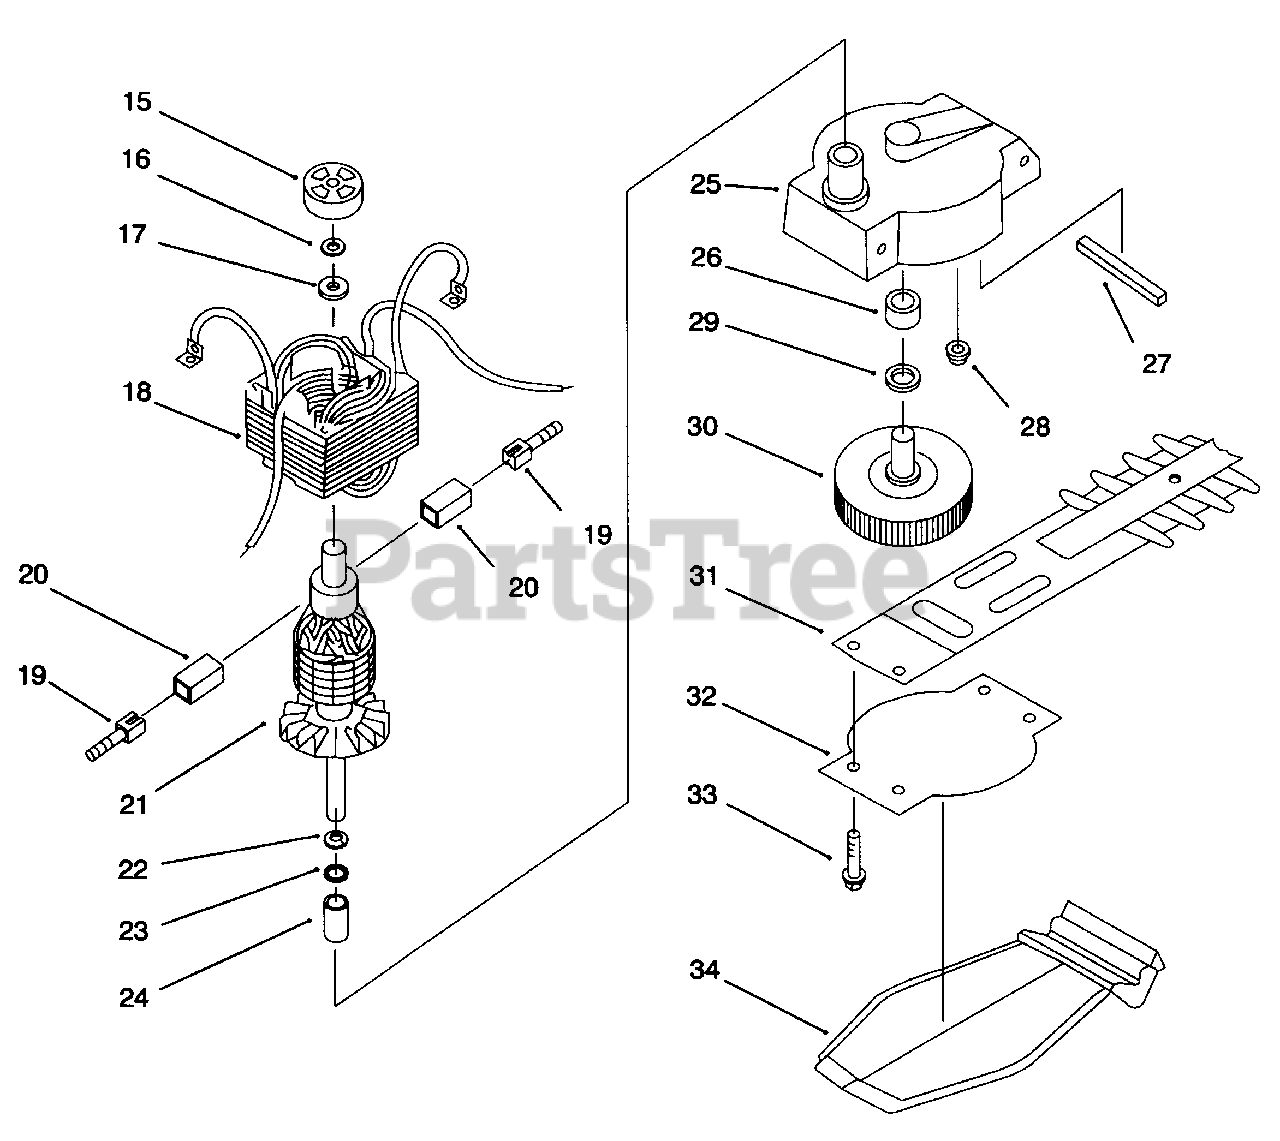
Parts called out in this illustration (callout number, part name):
15	SLEEVE BEARING
16	WASHER
18	FIELD ASSEMBLY
19	BRUSH ASSEMBLY
20	BRUSH TUBE
21	ARMATURE
22	SPRING WASHER
24	SLEEVE BEARING
25	GEAR HOUSING W/BEARINGS (INCL. REF. #24, 26 & 28)
26	SLEEVE BEARING
27	BLADE SEAL
30	GEAR ASSEMBLY
31	BLADE ASSEMBLY (51803)
32	GREASE COVER
34	BLADE COVER
